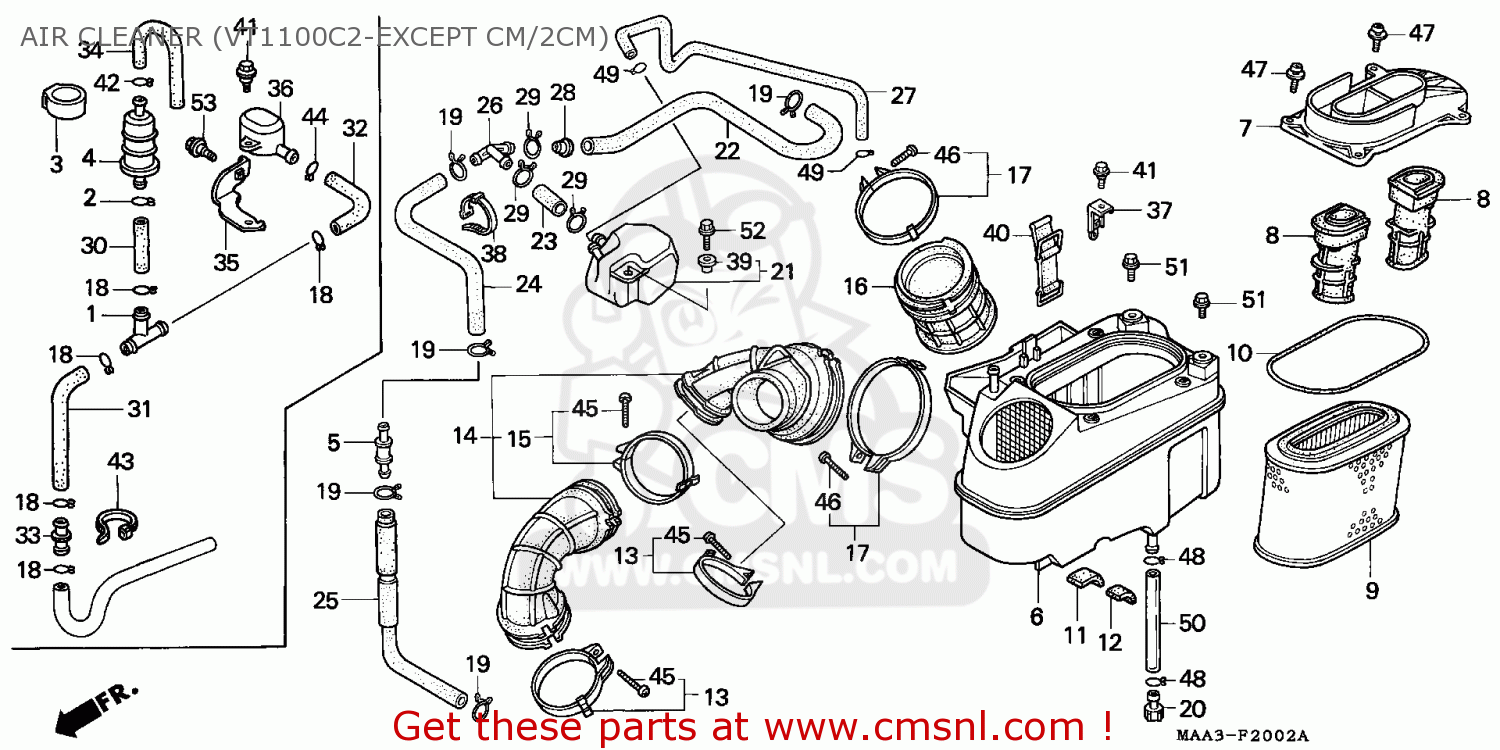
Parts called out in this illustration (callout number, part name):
5	JOINT,FUEL TUBE
6	CASE,SUB COMP.,AI
7	COVER,AIR/C CASE
8	DUCT,AIR CLEANER
9	ELEMENT,AIR/C
10	PKG,AIR/C CASE CO
11	RUBBER A,CUSHION
12	RUBBER B,CUSHION
13	BAND A,CONN TUBE
14	CONN TUBE A,
15	BAND B,CONNECTING
16	TUBE B,AIR CLEANE
17	BAND C,CONNECTING
19	CLIP,BRTHR.TUBE
20	PLUG,BRTHR TUBE
21	TANK,STORAGE
22	TUBE A,BREATHER
23	TUBE B,BREATHER
24	TUBE C,BREATHER
25	TUBE D,BREATHER
26	JOINT,BREATHER 3W
27	TUBE E,BREATHER
28	RUBBER,BREATHER P
29	CLIP,TANK HOSE
37	STAY,FILLER NECK
38	BAND,WIRE
39	COLLAR,FR.FENDER
40	BAND, SIDE COVER
41	BOLT,SOCKET,6X15
45	SCREW,PAN,4X20
46	SCREW,PAN,4X25
47	SCREW,WASHER,5X16
48	CLIP B12,TUBE
49	CLIP,TUBE,B12.5
50	TUBE,VINYL,7X11X2
51	BOLT,FLANGE,6X10
52	BOLT,FLANGE,6X12
